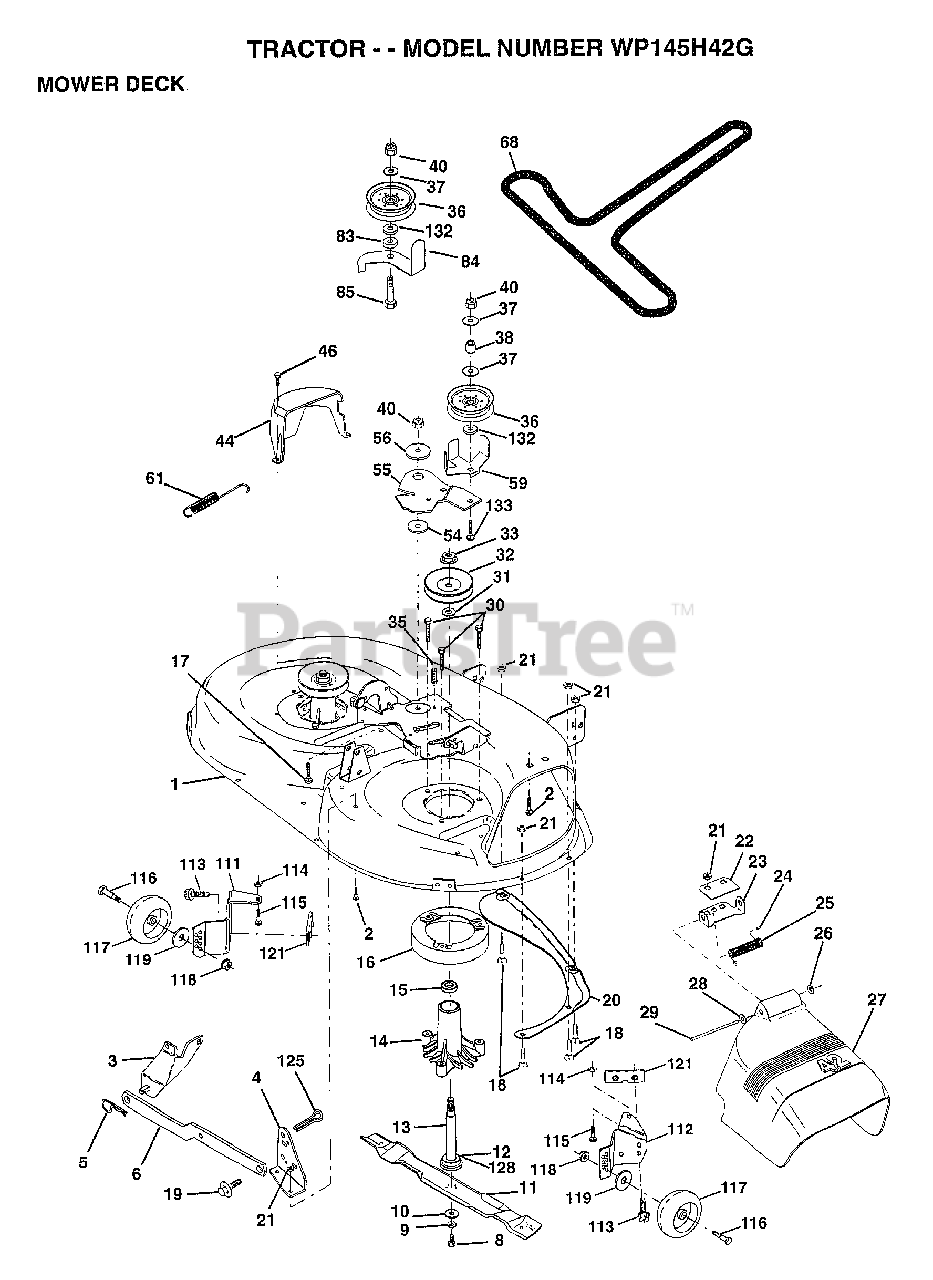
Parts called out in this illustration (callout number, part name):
1	"HOUSING ASSY.42"""
2	BOLT
3	BRKT ASM SWAY BAR
4	BRKT DECK SW BAR
8	BLADE BOLT
10	WASHER.HARD.BLADE
11	"BLADE.42"" HIPERF"
12	BEARING.BALL
14	HSG ASM MANDREL
15	BEARING
16	STRIPPER RND MWR
17	BOLT CARRIAGE
18	BOLT
19	BOLT SHD 5/16-18
20	BAFFLE VORTEX 42
22	STIFFENER BRKT
23	DEFLECTOR BRKT
24	CAP-SLEEVE LT
25	SPRING TORSION
26	NUT PUSH M
27	DEFLECTOR.SHIELD
28	WASHER
29	HINGE ROD
30	"SCREW-THD ROLL,WA"
31	WASHER
32	PULLEY.MANDREL.42
35	XMAS TREE FASTNER
36	FLAT IDLER PULLEY
37	WASHER
44	GUARD MAND LH BLK
46	SCREW.1/4-20X5/8
54	HARDENED WASHER
56	SPACER RETAINER
59	GUARD IDLER TUV
61	SPRING.EXTENSION
68	BELT.V.T-PATH
83	WASHER
84	"KEEPER-BELT,FIXED"
85	BOLT
111	BRACKET.GWHL.LH.
112	BRACKET.GWHL.RH.
113	SCREW
116	BOLT M
117	WHEEL.GUAGE
118	LOCKNUT
119	WASHER
121	BRACKET.EXTRD.GWL
125	COTTER PIN
128	WASHER.FELT.
132	WASHER GT
133	BOLT
